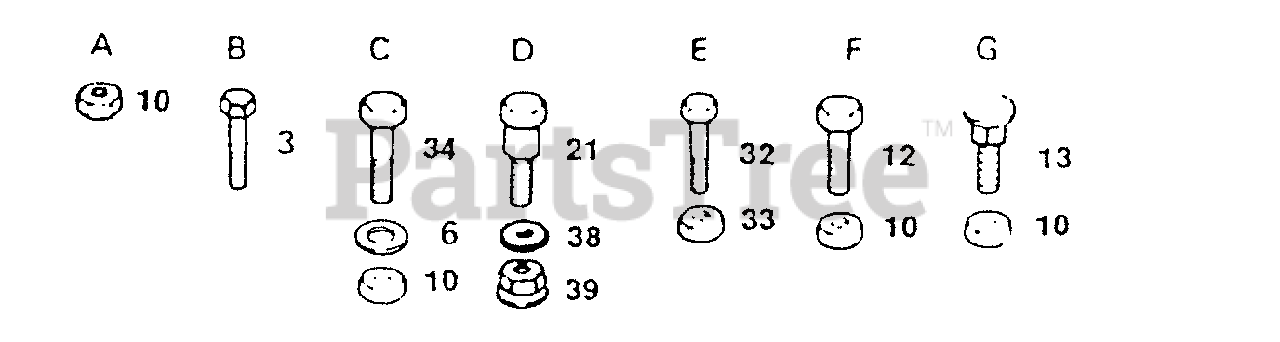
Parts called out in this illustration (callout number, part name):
3	Screw, Tap. Hex Hd. 10 - 24 x 1/2
6	Washer 13/32 x 13/16 x 12 Ga.
10	Nut, Crownlock 3/8 - 16
12	Bolt, Hex 3/8 - 16 x 3/4
13	Bolt,Rd.Hd.Sq Neck 3/8-16 x 3/4
21	Bolt, Shoulder 3/8 - 16
32	Bolt, Hex 5/16 - 18 x 3/4
33	Nut, Lock 5/16 - 18
34	Bolt, Hex 3/8 - 16 x 1
38	Washer, Spring
39	Nut, Flange Lock 3/8
